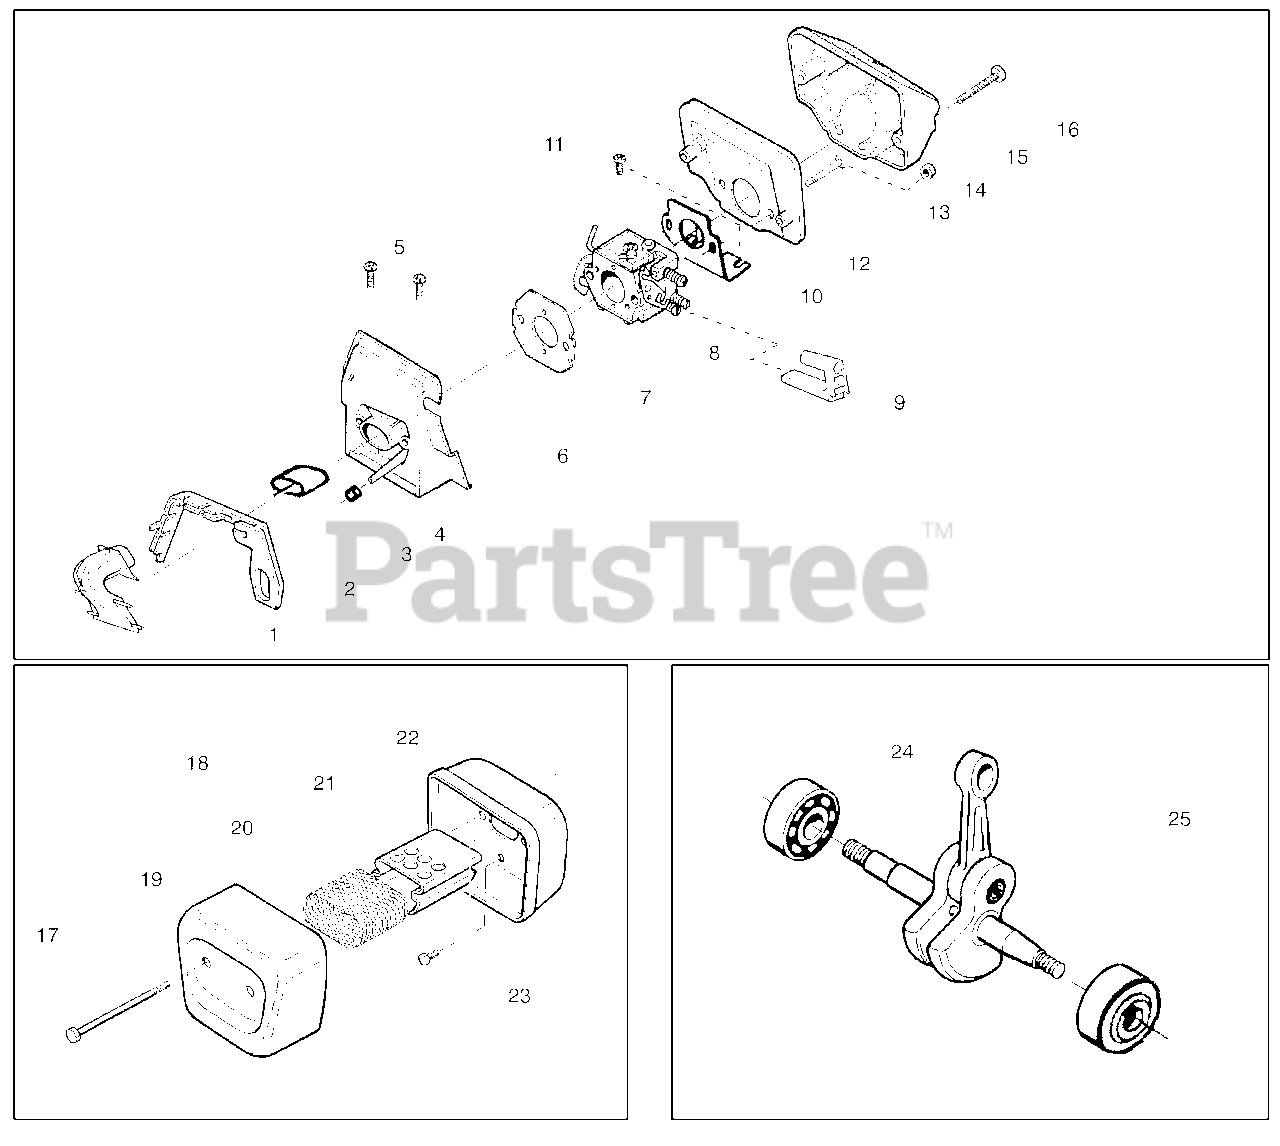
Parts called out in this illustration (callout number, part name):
1	Turbo Air Cleaner Assembly
2	Seal - Turbo Clean
3	Intake Sleeve
4	Impulse Seal
6	Adapter - Carb.
7	Carburetor Gasket
8	Carburetor
8	WT-542 (Walbro)
8	WT-289 (Walbro)
8	WT-540 (Walbro)
8	WT-660 US/Can/Mex
8	WT-660 Export Only
9	Grommet-Final
10	Plate - Support
12	Air Filter - Bottom
13	Stud - Carb.
15	Air-Filter - Top
18	Muffler Kit
19	Muffler Cover
20	Spark Arrestor Screen
21	Muffler Diffuser
22	Muffler Body
23	Muffler Bolt
24	Assy. -Bearing and Seal
25	Crankshaft & Rod Assembly
